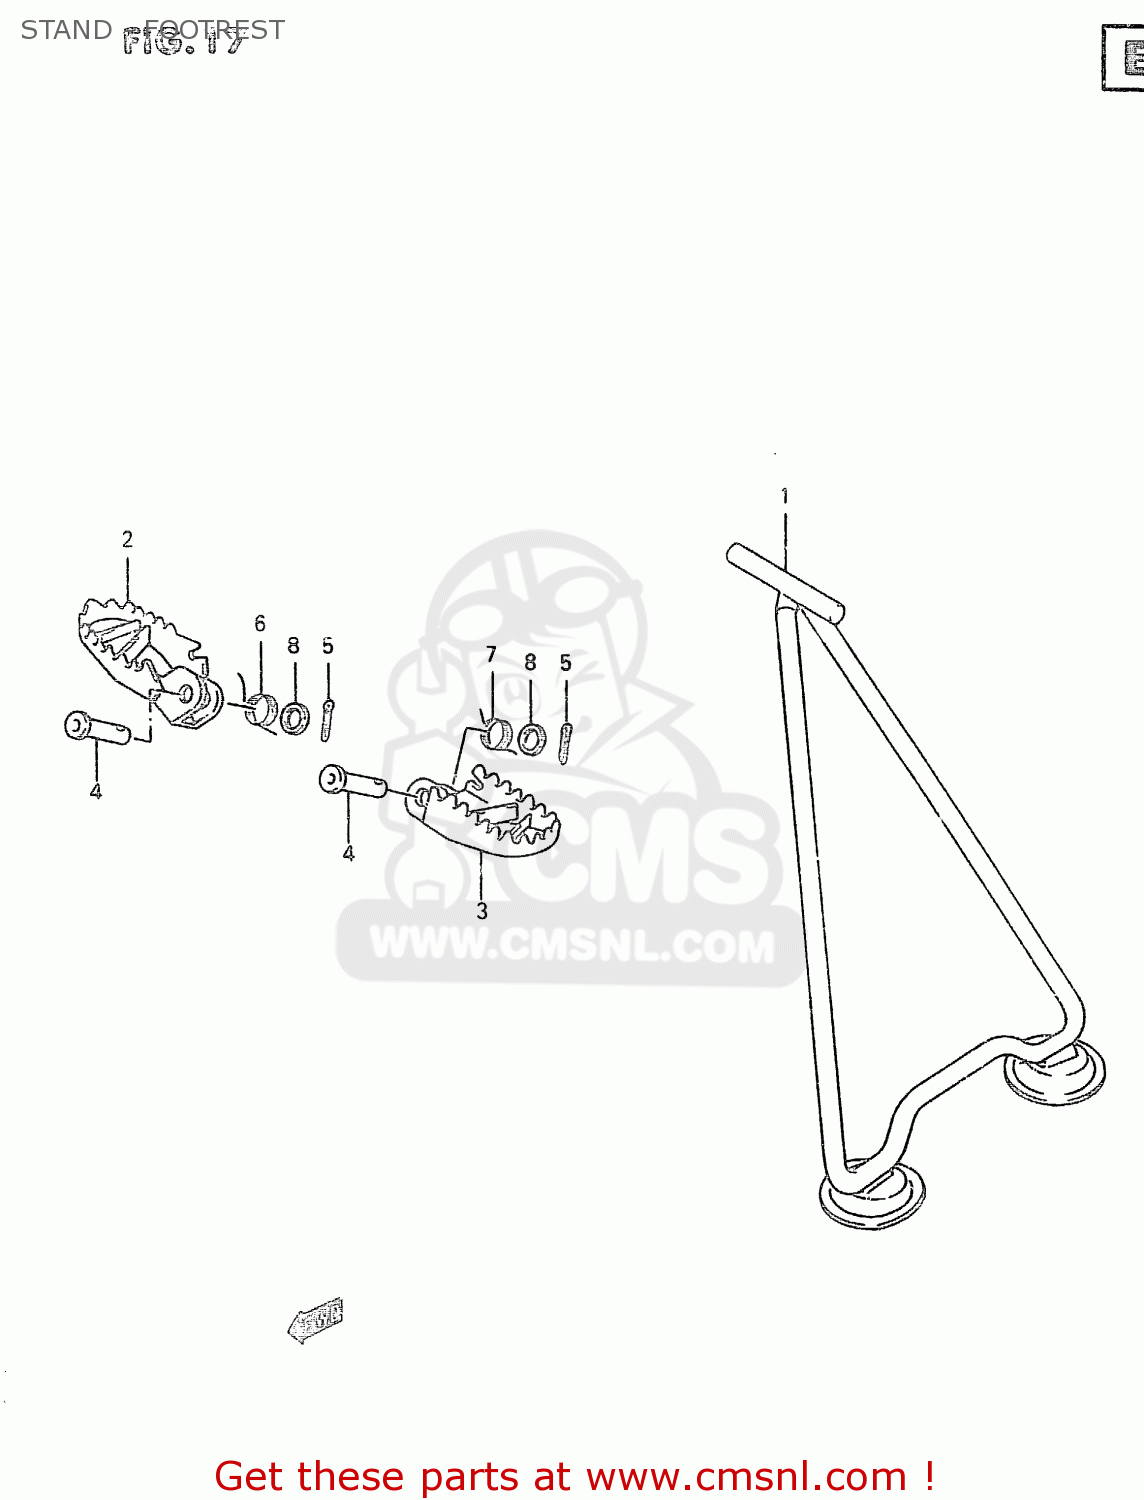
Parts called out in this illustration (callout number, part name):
1	STAND
2	FOOTREST,RIGHT
3	FOOTREST,L
4	PIN(10X41.5)
5	PIN 25X20
6	SPRING
7	SPRING
8	WASHER
